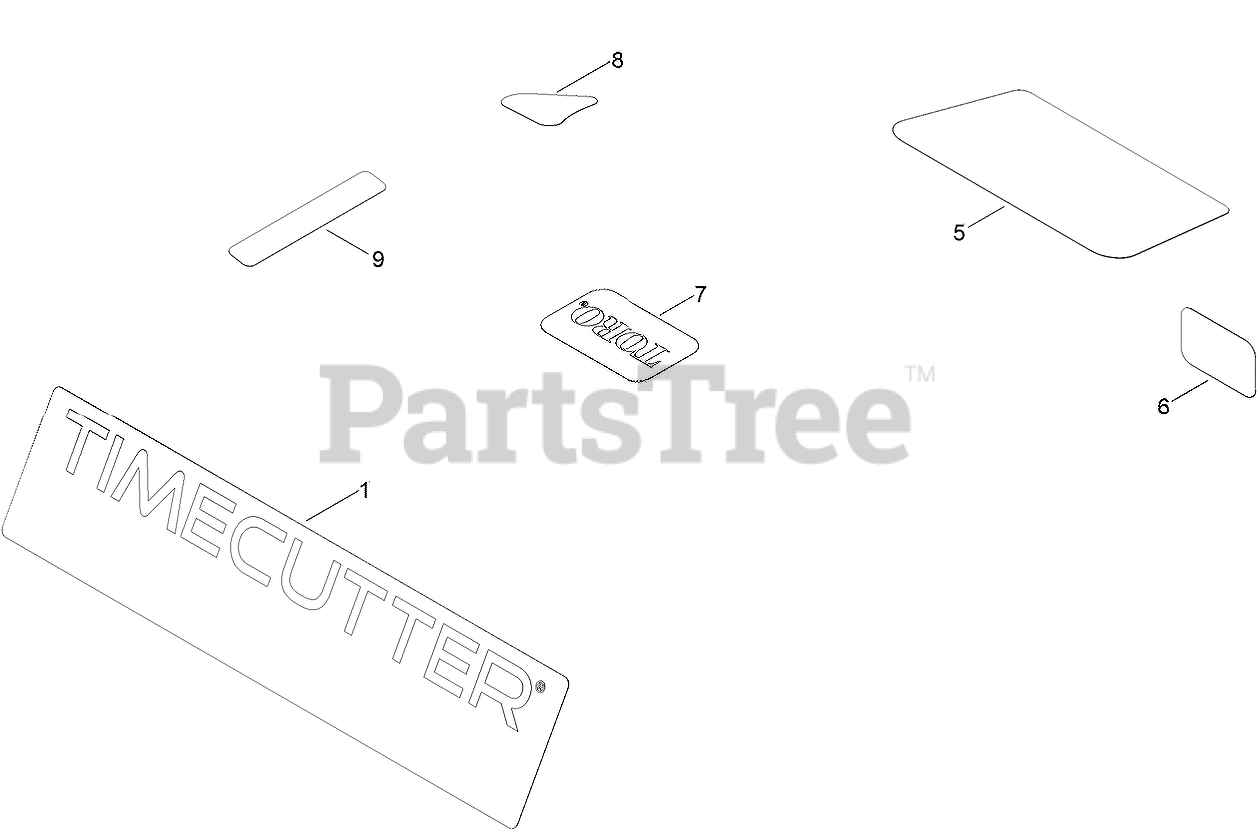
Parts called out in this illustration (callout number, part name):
1	DECAL-TIMECUTTER
5	DECAL-ENGINE
6	PLACARD-INTAKE
8	DECAL-DRAIN, OIL
9	DECAL-SHUTDOWN
